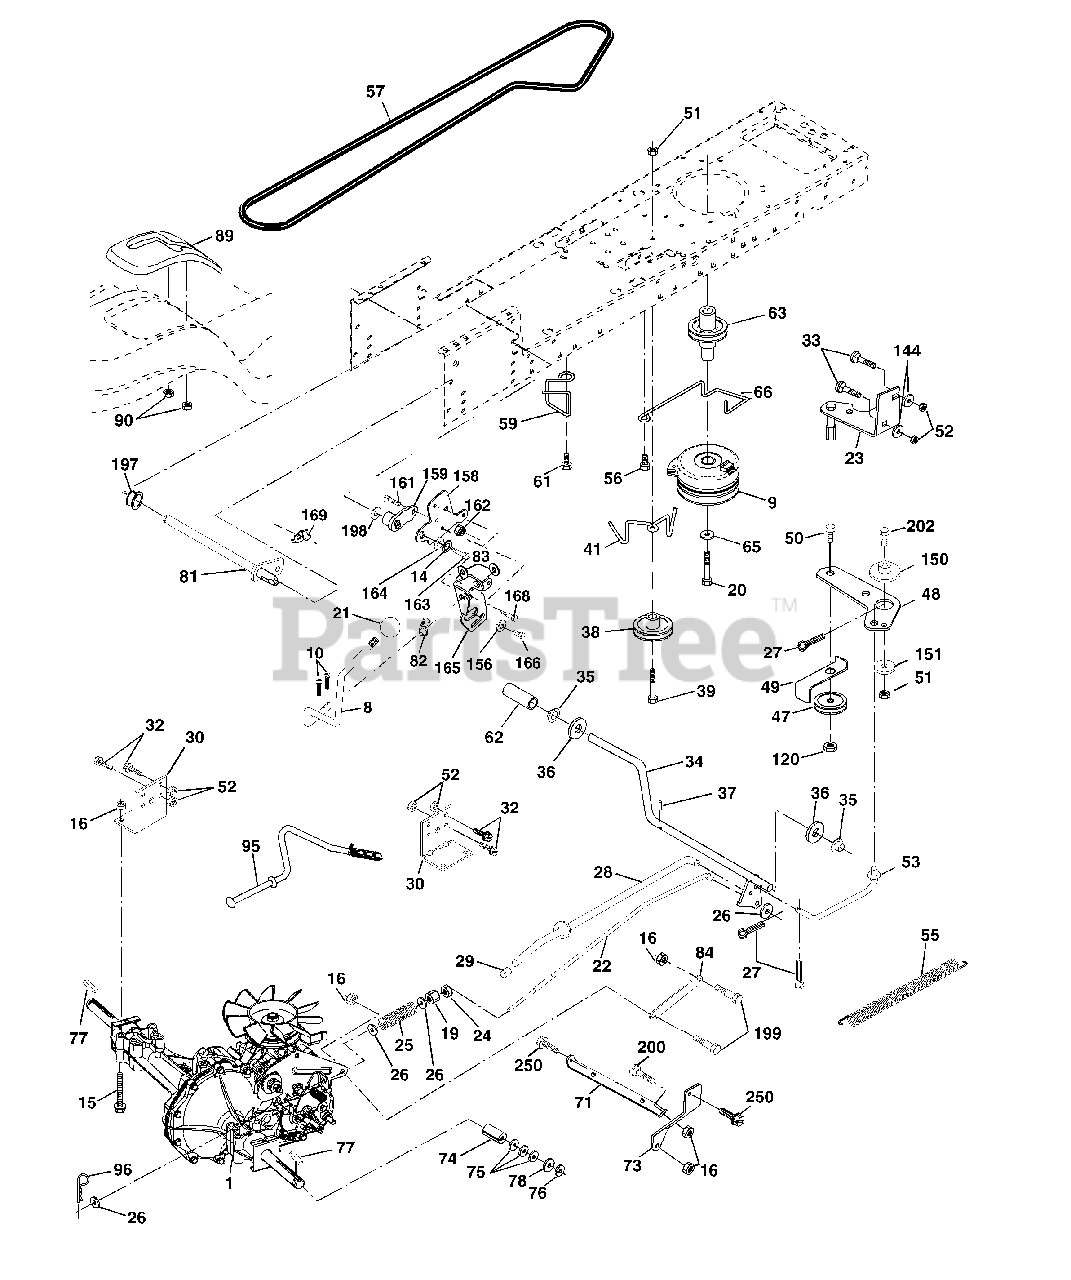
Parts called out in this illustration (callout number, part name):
8	Rod Shift Fender Adjust STLT
9	Clutch Electric
10	Pin Cotter 1/8 x 1 CAD
14	Washer Lock Hvy Helical
15	Bolt Hex 5/16-18 Unc Flghd
16	Nut Lock Hex W/Ins. 5/16-18 Unc P
19	Nut Lock Hex W/Ins 3/8-16 Unc
20	Bolt, Hex 7/16-20 x 4-1/4
21	Knob Deluxe 1/2-13 UNC BLK/BLK
22	Rod, Brake Hydro
23	Bracket Asm Anti-Rot EVX
24	Nut Hex Jam 3/8-16 UNC
25	Spring, Brake Rod
26	Washer
27	Pin Cotter 1/8 x 3/4 CAD.
28	Rod, Parking Brake
29	Cap,Parking Brake
30	Bracket, Transaxle
32	Bolt Hex Hd 5/16-18 Unc x 3/4
33	Bolt Carriage 5/16-18unc x 3/4
34	Shaft, Foot Pedal
35	Bearing, Nylon
37	Pin, Roll
38	Pulley, Composite, Flat
39	Bolt, Fin, Hex 3/8-16 x 3
41	Keeper, Belt Idler
47	Pulley, Idler, V-Groove Plastic
48	Bellcrank Clutch Grnd Drv STL
49	Retainer, Belt Style Spring
50	Bolt Hex Hd 3/8-16 Unc x 1-1/2
52	Nut Crown Lock 5/16-18
53	Link, Clutch
55	Spring, Return, Clutch
56	Screw 3/8-16 x 1.0
57	V-Belt, Ground Drive
59	Keeper, Center Span
61	Screw 3/8-16 x .875
62	Cover, Pedal
63	Pulley, Egine
65	Washer Lock Hvy HLCL Spr 7/16
66	Keeper Belt Engine
71	Strap Torque Lh Hydro
73	Strap Torque Rh Hydro
74	Spacer, Axle
75	Washer 25/32 x 1-1/4 x 16 Ga.
77	Key, Square
78	Washer 25/32 x 1-5/8 x 16 Ga
81	Shaft Asm Cross Tapered
82	Spring Torsion T/A
83	Washer 17/32 x 3/4 x 16 Ga.
84	Link Transaxle
89	Console, Shift
90	Nut Self Thd 1/4
95	Control Asm. Bypass Hydro
96	Retainer Spring 1" Zinc/Cad
120	Nut Lock Flg 3/8-16
144	Washer 11/32 x 5/8 x 16 Ga.
150	Spacer Retainer
151	Washer 13/32 x 2 x 10 Ga.
156	Washer Srrted 5/16ID x 1.125
158	Bracket Shift Mount
159	Hub Tapered Flange Shift Lt
161	Bolt Rdhd Sqnk 1/4-20 x 3/4 Gr 5
162	Nut Crownlock 1/4-20 Unc
163	Bolt Hex Fin 1/4-20 Unc x 1 Gr 5
164	Washer 5/8 x .281 x 10 Ga
165	Bracket Pivot Lever
166	Screw 5/16-18 x 5/8
168	Bolt Shoulder 5/16-18 x .561
169	Plate Fastening STLT/CRD
197	Nyliner Snap 5/8" ID
198	Washer Nyl 7/8 ID x .105 Hyd
199	Bolt Shoulder 5/16-18 Unc
200	Bolt Rdhd Sqnk 5/16-18 Unc x 1
202	Bolt 3/8-16 Unc x 1-3/4 Gr. 5
250	Screw 3/8-16 x .75
